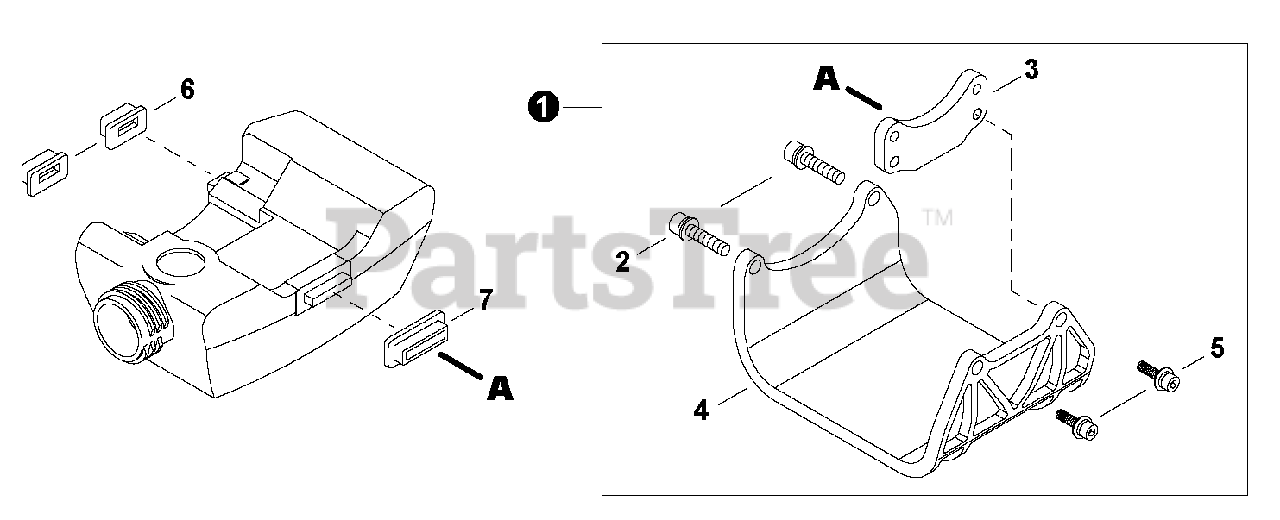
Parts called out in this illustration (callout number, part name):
1	TANK GUARD ASSY - PLASTIC
2	BOLT M5×30
3	BRACKET, FUEL TANK
4	GUARD, FUEL TANK
5	BOLT 5×20
6	CUSHION, FUEL TANK
7	CUSHION, FUEL TANK - REAR
